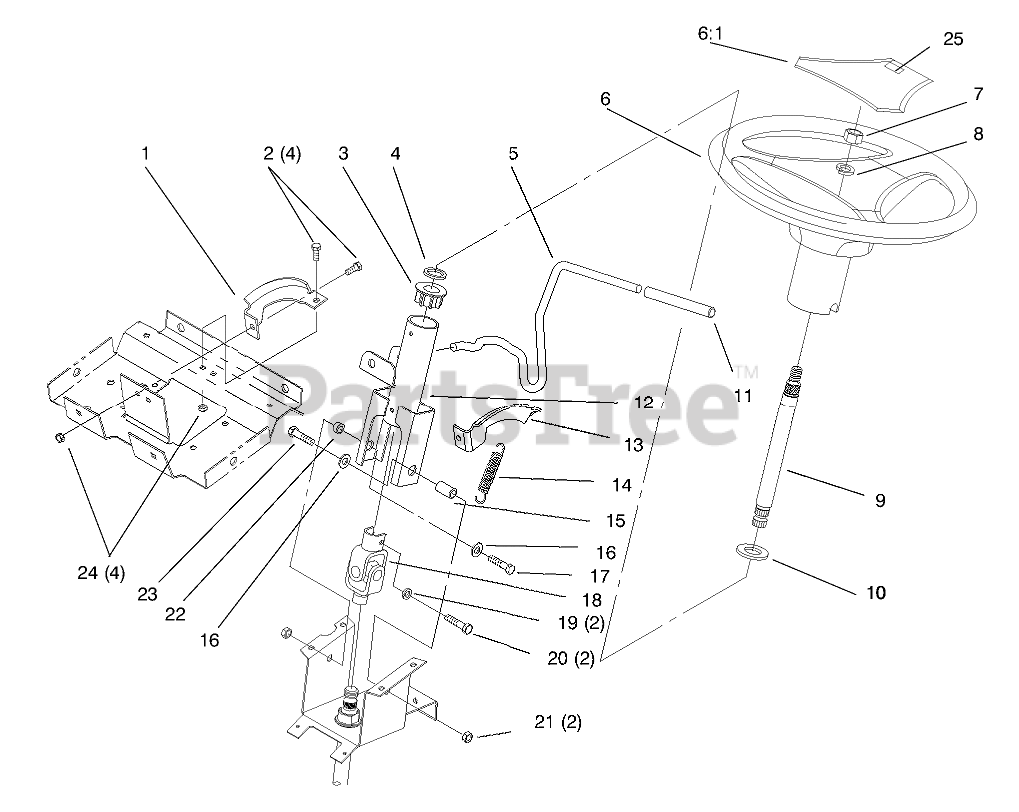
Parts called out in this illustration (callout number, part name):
1	BRACKET-SUPPORT, COLUMN
2	SCREW-HH
3	BUSHING-STEERING, UPPER
4	WASHER-BOWED
5	LEVER-TILT
6	WHEEL-STEERING
6:1	COVER-WHEEL, STEERING
7	NUT-HH
8	WASHER-LOCK
9	SHAFT-SHORT, STEERING
10	WASHER-FLAT
11	CAP-ROD, TILT
12	COLUMN ASM
13	BRACKET-DETENT
14	SPRING-EXTENSION
15	SPACER-YOKE
16	WASHER-PLAIN
17	SCREW-HH
18	U-JOINT, STEERING
19	WASHER-LOCK
20	SCREW-HH
21	NUT-LOCK, NI
22	SPACER-YOKE, RIGHT
23	SCREW-HH
24	NUT-HEX
25	DECAL
